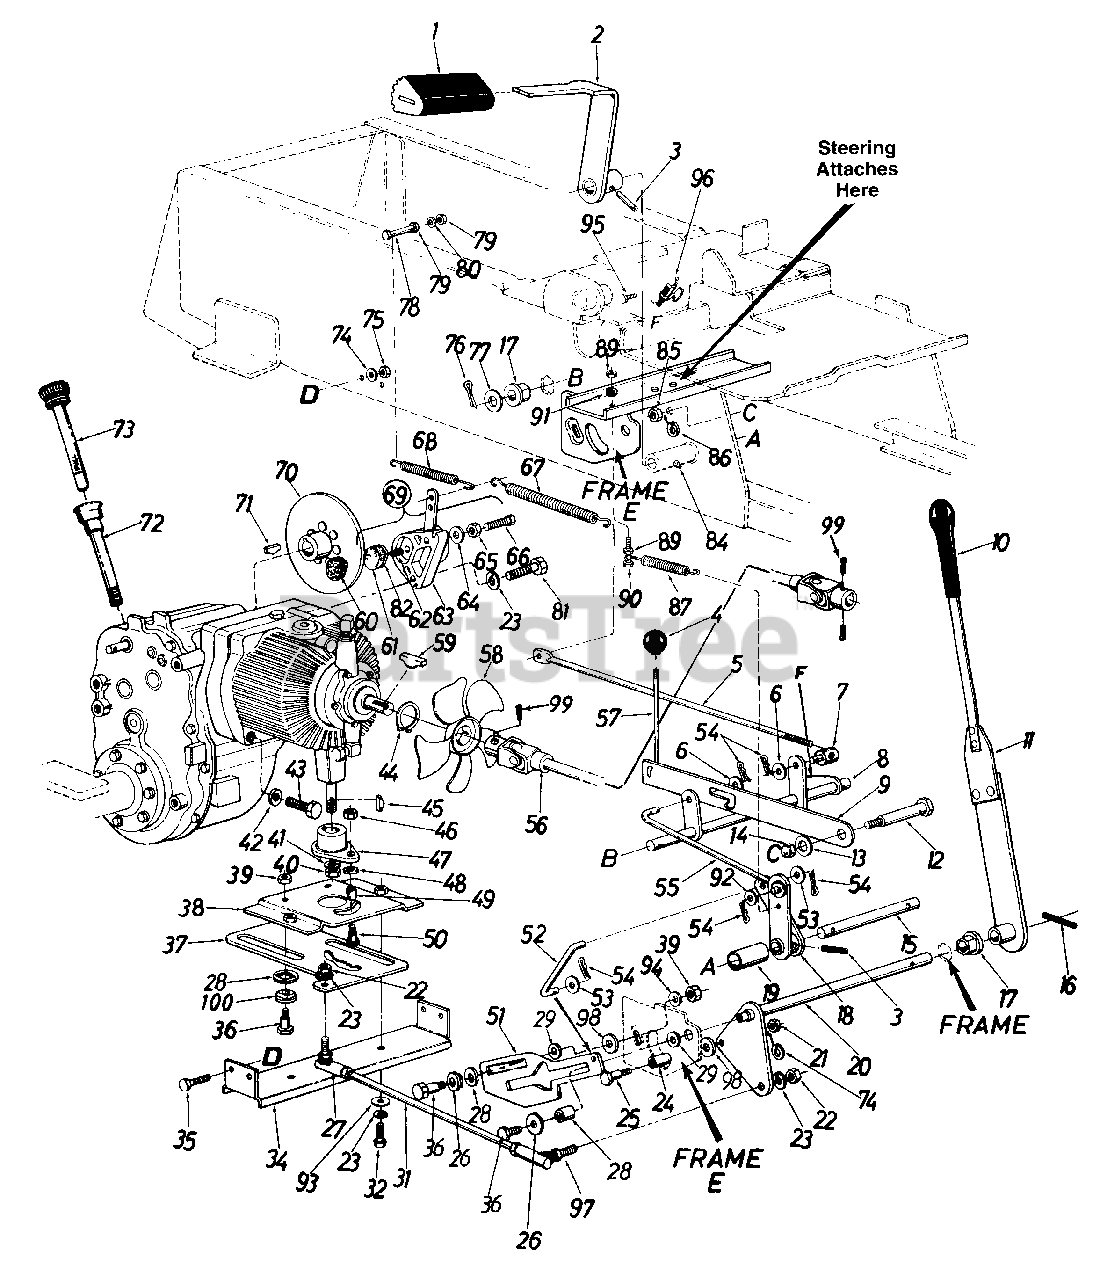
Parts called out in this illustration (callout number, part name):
1	Foot Pad
4	Ball Knob - Brake
5	Brake Rod
6	Fl-Wash .375" I.D. x 1.00" O.D. x .030"
7	Ferrule
8	Brake Transfer Shaft Ass'y.
9	Parking Brake Cam
11	Control Arm Ass'y. Comp.
12	Shld. Bolt .62" Dia. x 2.75" Lg.
13	Fl-Wash .460" I.D. x 1.24" 0 D. x .06"
14	Push Speed Nut for .625" Dia. Shaft
15	Brake Pivot Shaft
16	Spring Pin Spiral 1/4" Dia. x 1.50" Lg.
17	Hex Flange Brg. Plastic .62" I.D.
18	Brake Lever Ass'y.
19	Spacer
20	Control Handle Shaft Ass'y.
21	Hex Cent. L-Nut 5/16-18 Thd.
22	Hex Nut 3/8-24 Thd.
23	L-Wash. 3/8" I.D.
24	Spacer
25	Shoulder Bolt
26	Fl-Wash. 7/16" I.D. x 1-3/8" O.D.
27	Ball Joint Ass'y. 3/8-24 Thd. - L H.
28	Spacer
29	Fl-Wash .325" I.D. x 1.25" O.D.
31	Tie Rod
32	Hex Bolt 3/8-16 x .75" Lg.
34	Support Channel
35	Hex Bolt 5/16-18 x .75" Lg.
36	Shld. Bolt .437" Dia. x .268"
37	Cam Plate
38	Slide Mtg. Plate Ass'y.
39	Hex L-Nut 5/16-18 Thd.
40	Hex Nut 1/2-13 Thd.
41	L-Wash. 1/2" I.D.
42	Fl-Wash .385" I.D. x .87" O.D. x .060"
43	Socket Hd. Scr. 3/8-16 x 2.75" Lg.
44	Snap Ring
45	#5 Hi-Pro Key 1/8" x 5/8" Dia.
46	Hex Cent. L-Nut 1/4-20 Thd.
47	Pintle Plate Ass'y.
48	Fl-Wash .281" I.D. x .50" O.D. x .063"
49	Needle Brg .31" I D. x .50" O.D. x 437" Lg.
50	Shld. Bolt 31" Dia. x .500
51	Neutral Control Slide
52	Neutral Control Rod
53	Fl-Wash .312" I D x 630" O.D. x .063"
54	Hairpin Cotter
55	Brake Link Rod Ass'y
56	Universal Drive Shaft Comp.
57	Parking Brake Link
58	Fan Ass'y.
59	#61 Hi-Pro Key 3/16 x 5/8" Dia.
60	Lining - Brake
61	Lining - Brake
62	Actuator Pin
63	Housing with Lever and Pin
65	Nut
66	Adjustment Pin
67	Extension Spring .50" O.D. x 6.5" Lg.
68	Extension Spring (Brake Return)
69	Disc Brake Ass'y. Comp.
70	Brake Disc Ass'y.
71	Hi-Pro Key 3/16 x 3/4" Dia.
72	Dipstick Tube Ass'y.
73	Dipstick Ass'y.
74	L-Wash. 5/16" I.D.
75	Hex Nut 5/16-18 Thd.
76	Cotter Pin 1/8" Dia. x 1.00" Lg.
77	Fl-Wash .635" I.D. x 1.00" O.D. x .120" Thk.
78	Hex Scr. 1/4-20 x 2.50" Lg.
79	Hex Nut 1/4-20 Thd.
80	L-Wash. 1/4" I.D
81	Hex Bolt 3/8-16 x 1.25" Lg.
82	Backing Plate
84	Grease Fltting
85	Hex Nut 7/16-20 Thd.
86	L-Wash. 7/16" I.D.
87	Extension Spring
89	Hex Nut 1/4-20 Thd.
90	Hex Bolt 1/4-20 x 1.25" Lg.
91	L-Wash. 1/4" I.D.
92	Fl-Wash.
93	Fl-Wash .38" I.D x 1.25" O.D.
94	Bell-Wash.
95	Hex Bolt 1/4-20 x .5" Lg.
96	Safety Switch
97	Ball Joint Ass'y. 3/8-24 Thd. - R.H.
98	Fl-Wash .32" I D x .6" 0 D
100	Thrust Washer
